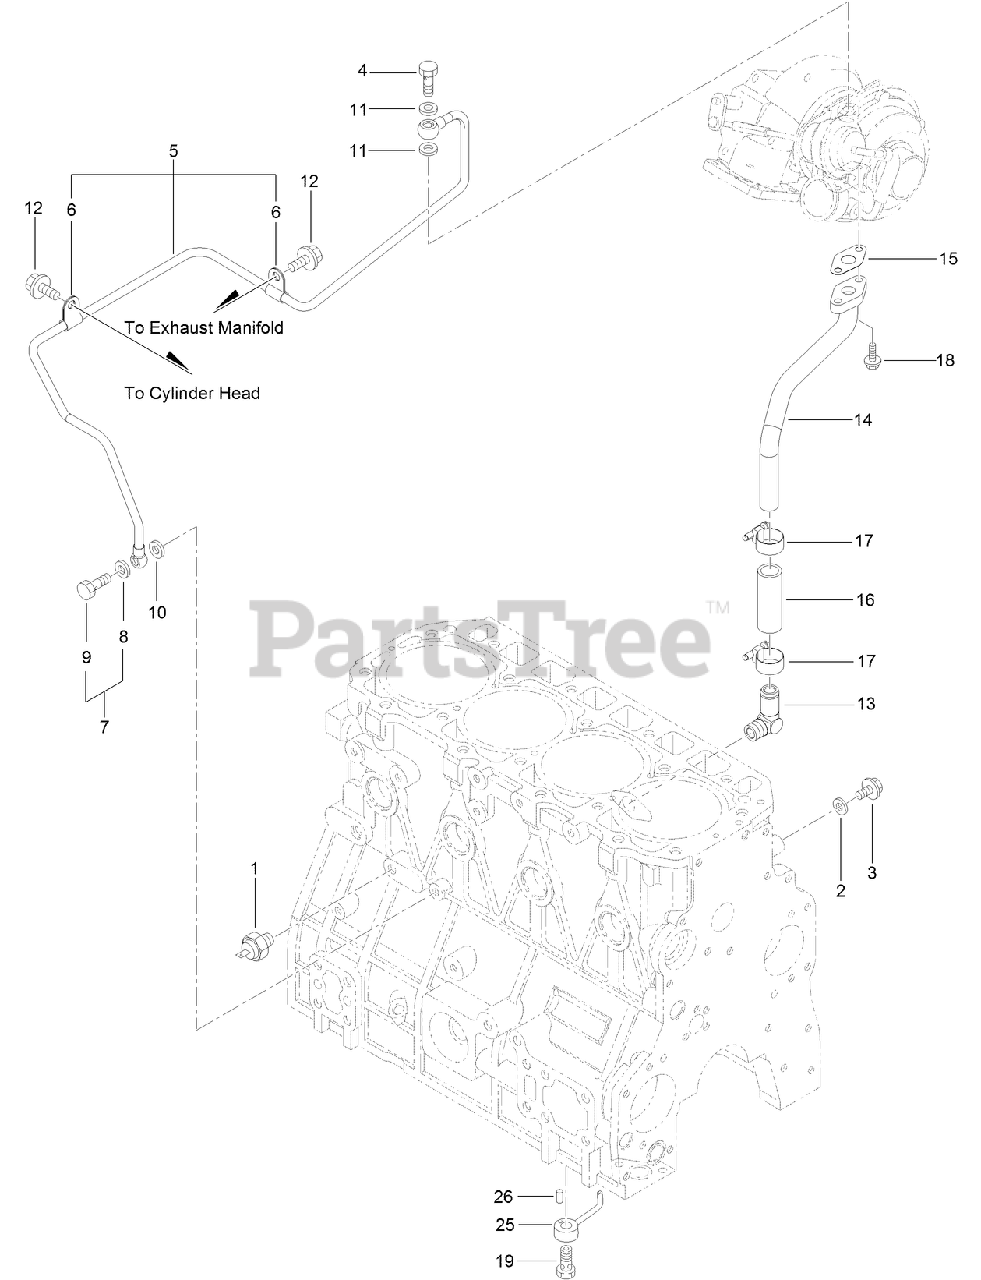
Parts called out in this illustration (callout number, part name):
1	SWITCH-OIL
2	WASHER-SEAL
4	BOLT-JOINT, PIPE
5	L O PIPE ASM
6	RETAINER
7	JOINT BOLT ASM
8	WASHER-SEAL
9	BOLT-JOINT
10	WASHER-SEAL
11	GASKET
14	PIPE-L O RETURN T/C
15	GASKET
17	CLAMP-HOSE
19	CHECK VALVE ASM
25	NOZZLE
26	PIN-SPRING
